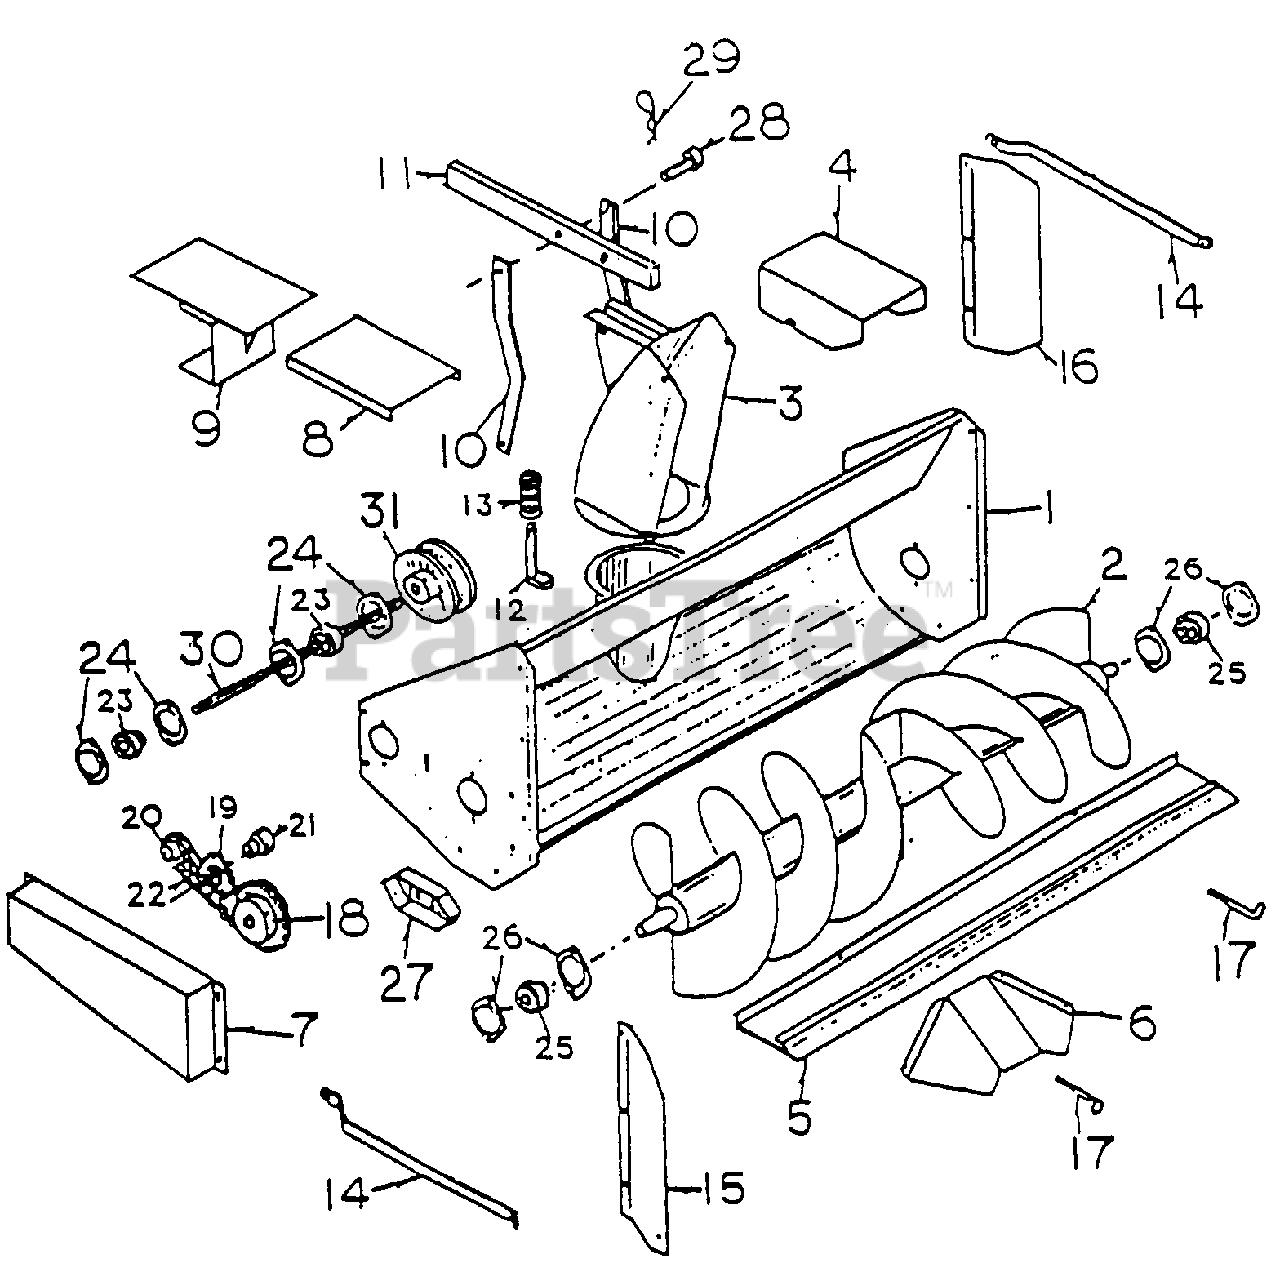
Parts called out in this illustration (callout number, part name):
1	Snow Blower Housing
2	Auger
3	Chute
4	Snow Deflector
7	Chain Guard
8	Belt Guard
9	Belt Retainer
10	Chute Lock Linkage
11	Handle
12	Chute Lock
13	Chute Lock Spring
14	Extended Braces
15	R.H. Extender
17	Blade Bolt
18	Auger Sprocket
19	Idler Sprocket
20	Drive Sprocket
21	Idler Sprocket Bushing
24	3/4 Bearing Flange
25	l in. Bearing
26	l in. Bearing Flange
30	Shaft
